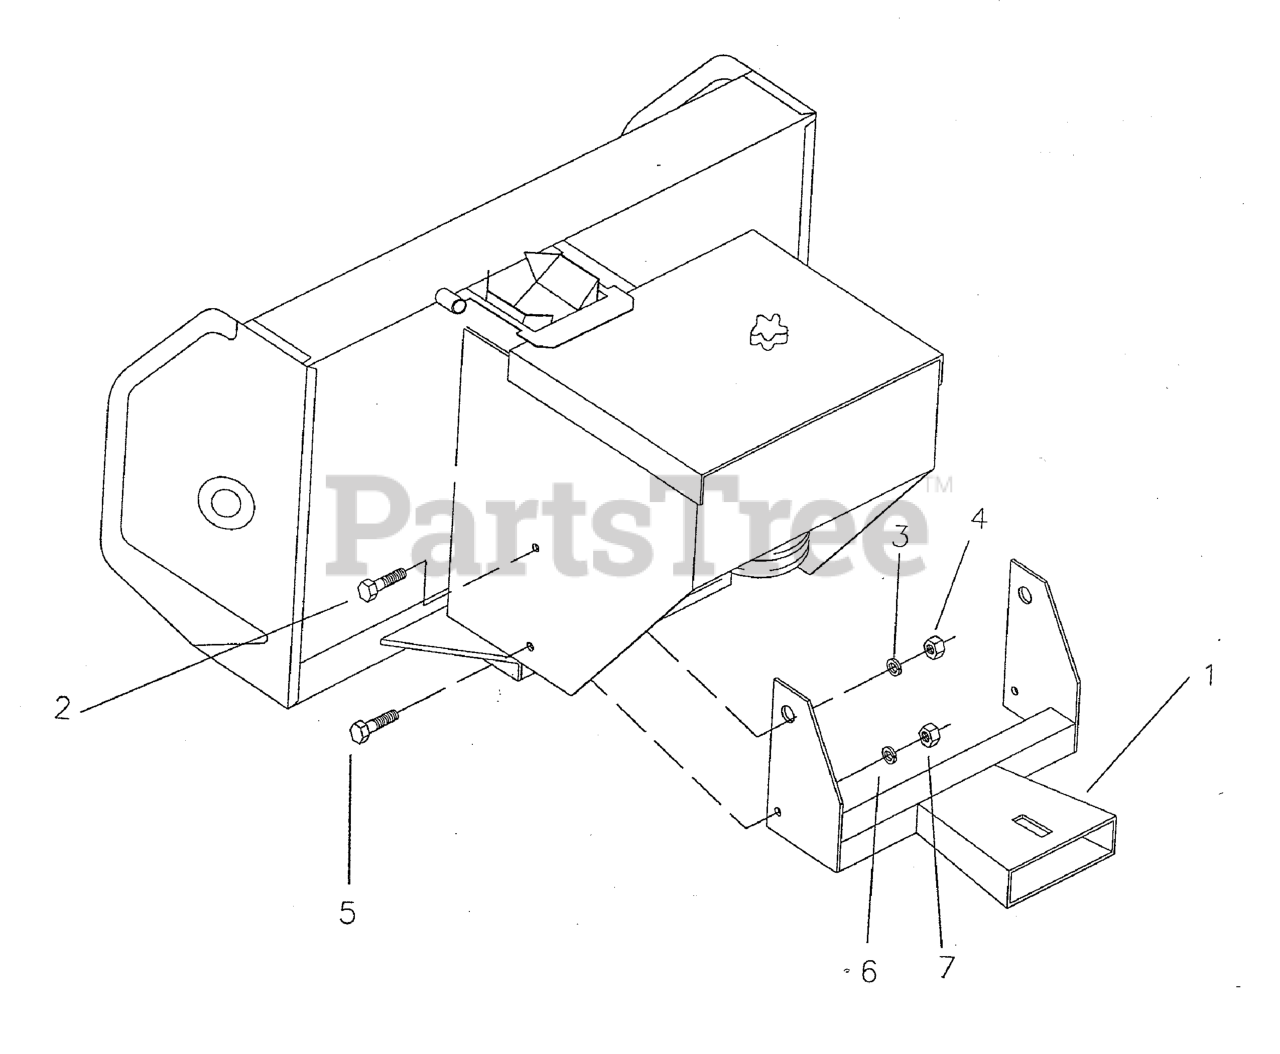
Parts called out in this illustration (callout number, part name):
1	Female Quick Hitch
4	Hex Nut 3/8" NC
7	Hex Nut 1/2" NC
